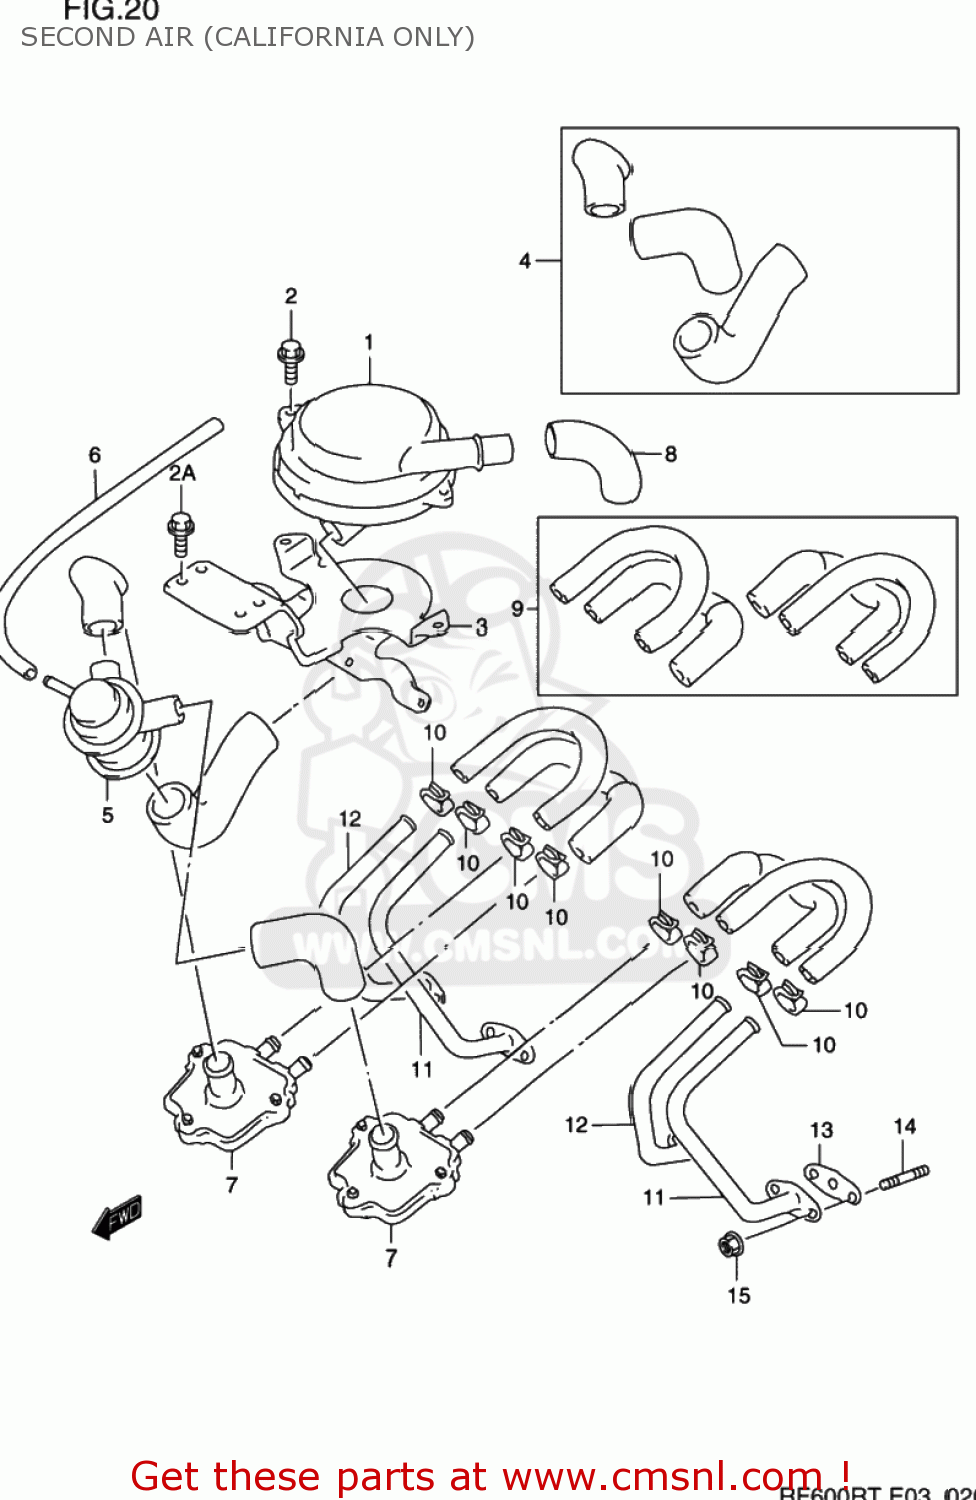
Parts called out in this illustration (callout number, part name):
1	CLEANER ASSEMBLY,SECOND AIR
2	BOLT
2A	BOLT
3	BRACKET COMP,SECOND AIR
4	HOSE SET,2ND AIR NO.2
5	VALVE ASSEMBLY,SECOND AIR SWITCH
6	HOSE (4.5X8.5X600)
7	VALVE ASSY,2ND AIR REED
8	(CA) HOSE,SECOND AIR CLEANER
9	HOSE SET,2ND AIR NO.1
10	CLIP
11	PIPE COMP,SECOND AIR NO.1
12	PIPE COMP,SECOND AIR NO.2
13	GASKET,SECOND AIR PIPE (N (NAS)
14	STUD BOLT
15	NUT
